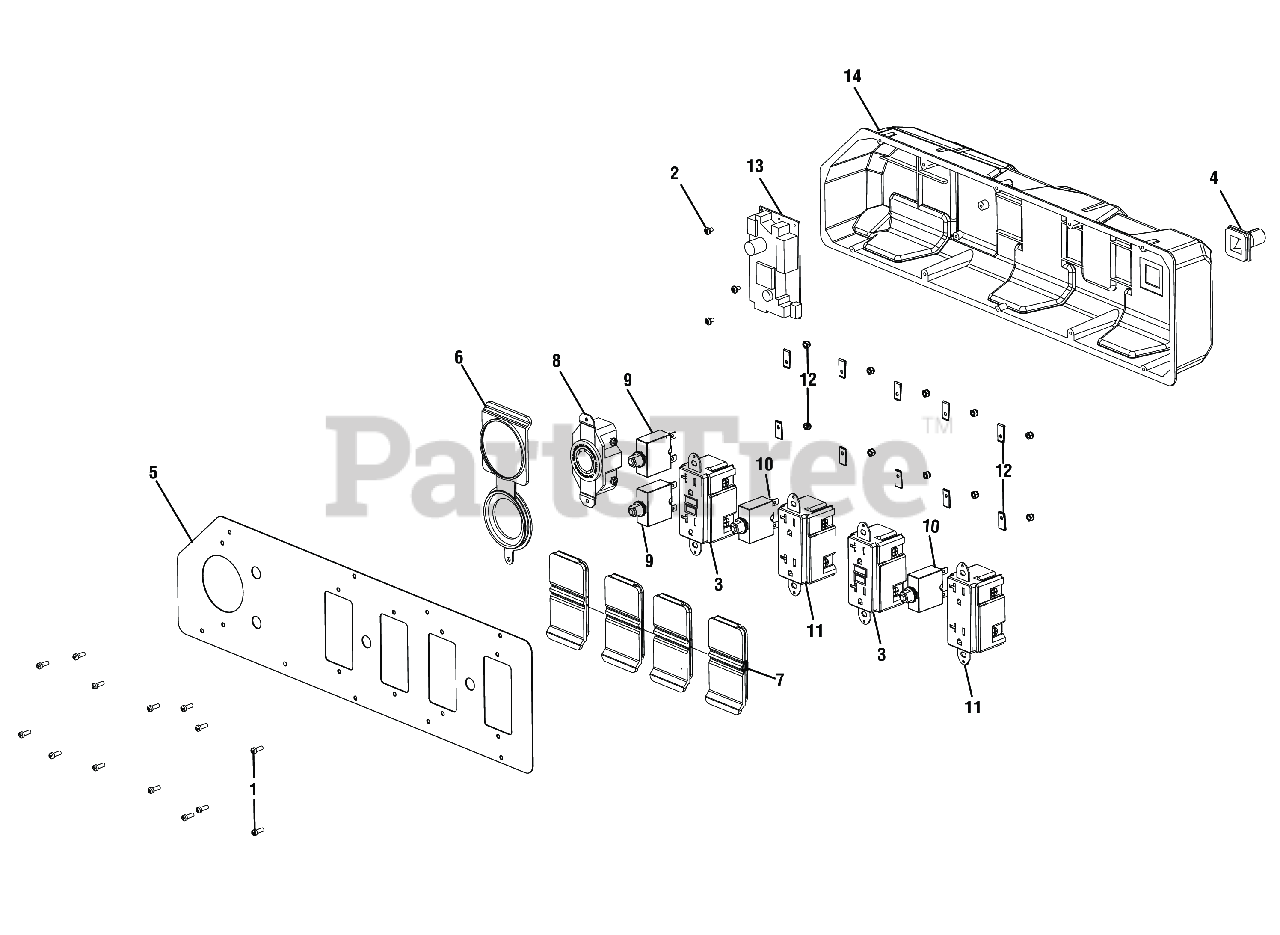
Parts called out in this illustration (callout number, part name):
1	Screw (6-20 x 3/8 in., Phillips Pan Hd.)
2	Screw (M3 x 5 mm, T10 Torx Pan Hd.)
3	120 Volt Duplex GFCI Receptacle
4	Rubber Boot (Control Panel Assembly)
5	Control Panel Faceplate
6	Twist Lock Receptacle Cover
7	120V Duplex Receptacle Cover
8	Twist Lock Receptacle (120/240 Volt, 30 Amp, L14-30R)
9	Circuit Breaker (30 Amp)
10	Circuit Breaker (20 Amp, 125 Volt)
11	Duplex Receptacle (120/240 Volt, 20 Amp)
12	Lock Nut (6-32, Hex Hd.)
12	U- Clip Nut (#6)
13	Battery Charger Assembly
14	Control Box
